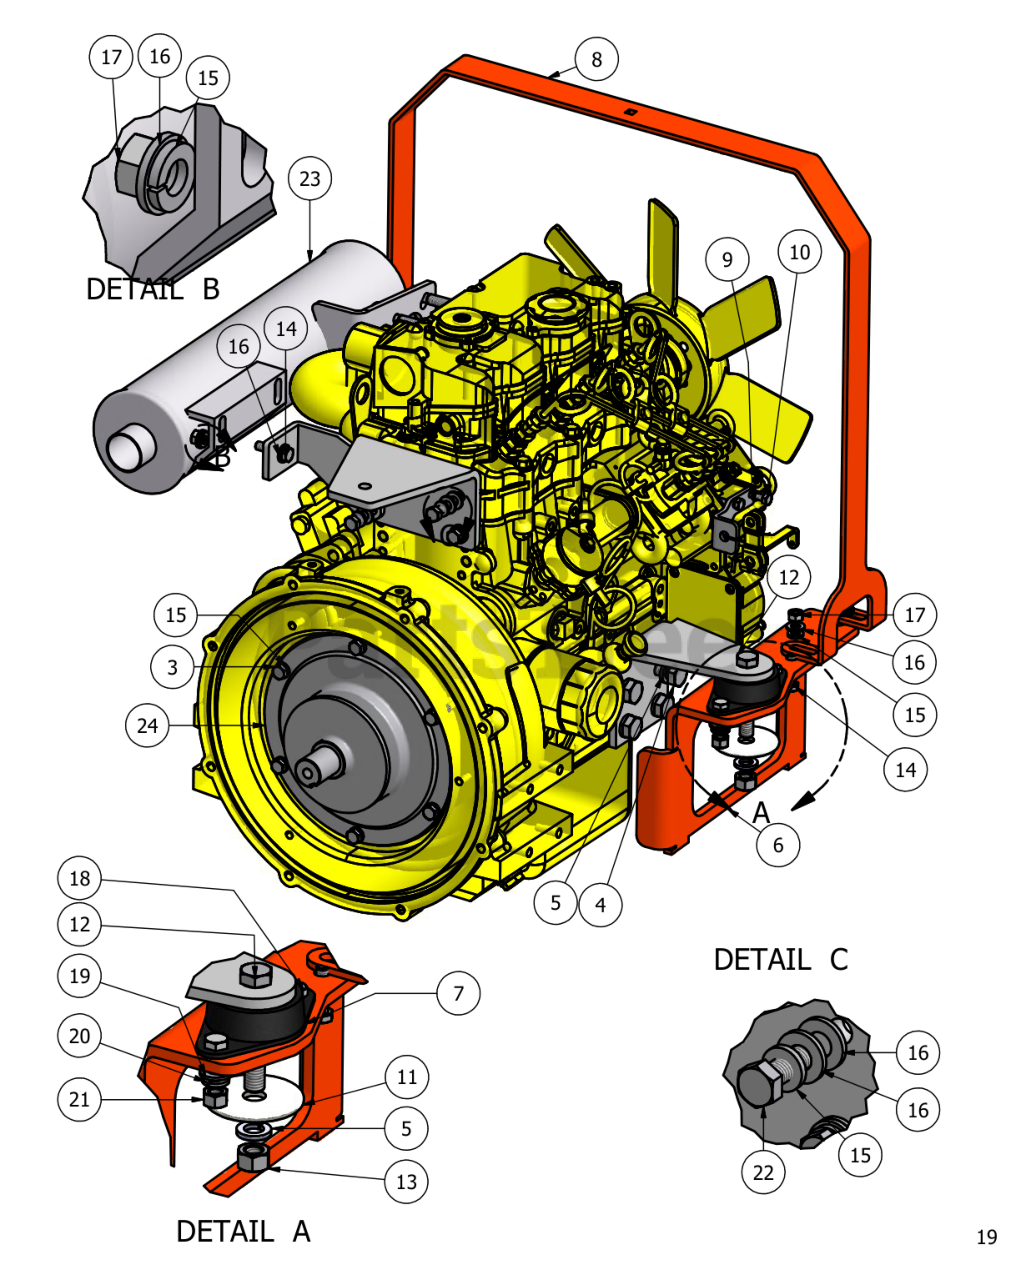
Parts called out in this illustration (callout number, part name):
1	28hp Caterpillar Engine
2	35hp Caterpillar Engine
3	5/16" x 1" Bolt
4	12mm x 25mm Bolt
5	1/2" Lock Washer
6	28hp Diesel Frame
6	35hp Diesel Frame
7	Rubber Isolator
8	Hood Holder
9	1/4" Lock Washer
10	6mm x 20mm Bolt
11	Snubbing Washer
12	1/2" x 3" Hex Bolt
13	1/2" Hex Nut
14	5/16" x 1 1/4" Hex Bolt
15	5/16" Lock Washer
16	5/16" Flat Washer
18	3/8" x 1" Hex Bolt
19	3/8" Flat Washer
20	3/8" Lock Washer
21	3/8" Hex Nut
22	8mm x 25 Bolt
23	Diesel Muffler
24	Stub Shaft
